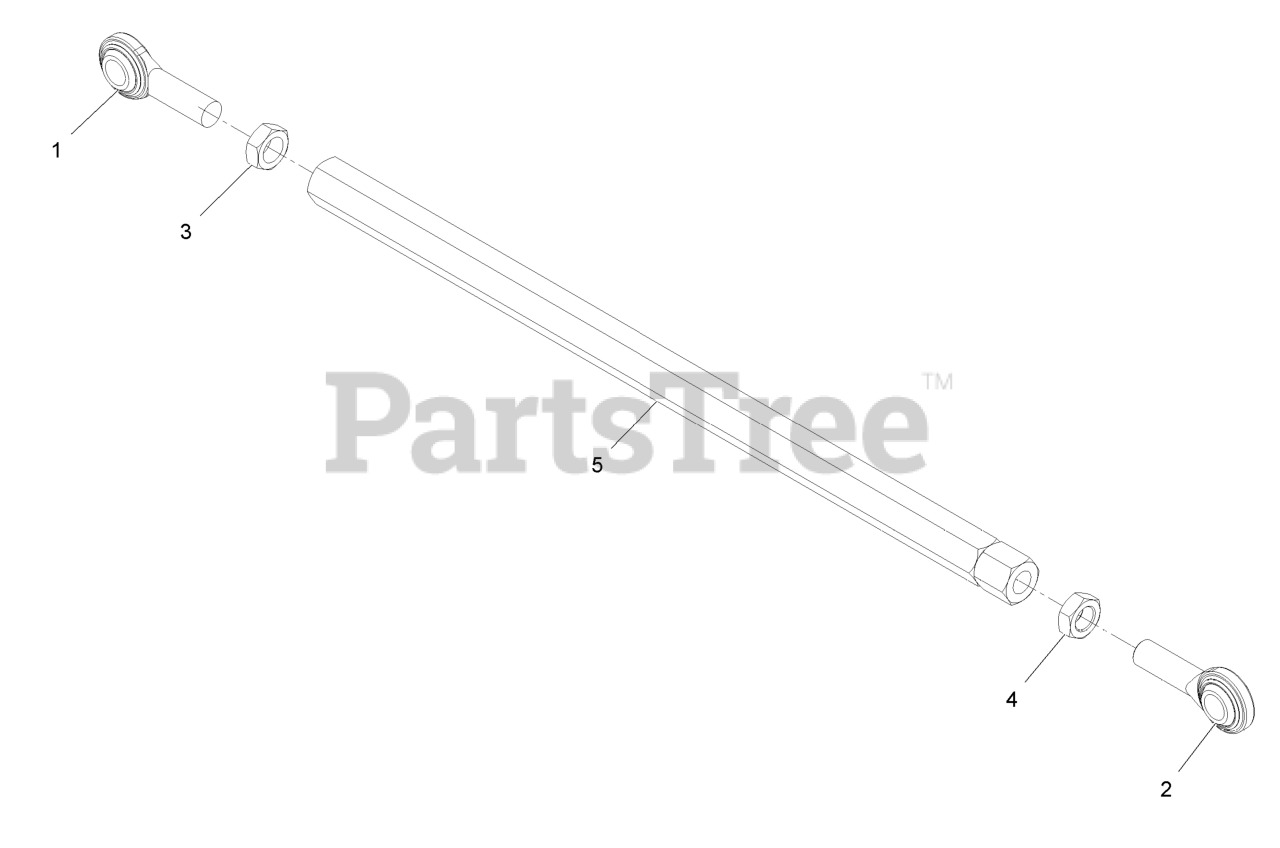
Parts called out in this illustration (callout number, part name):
1	BALLJOINT-SPHERICAL
2	BALLJOINT-SPHERICAL
3	NUT-JAM
4	NUT-JAM
